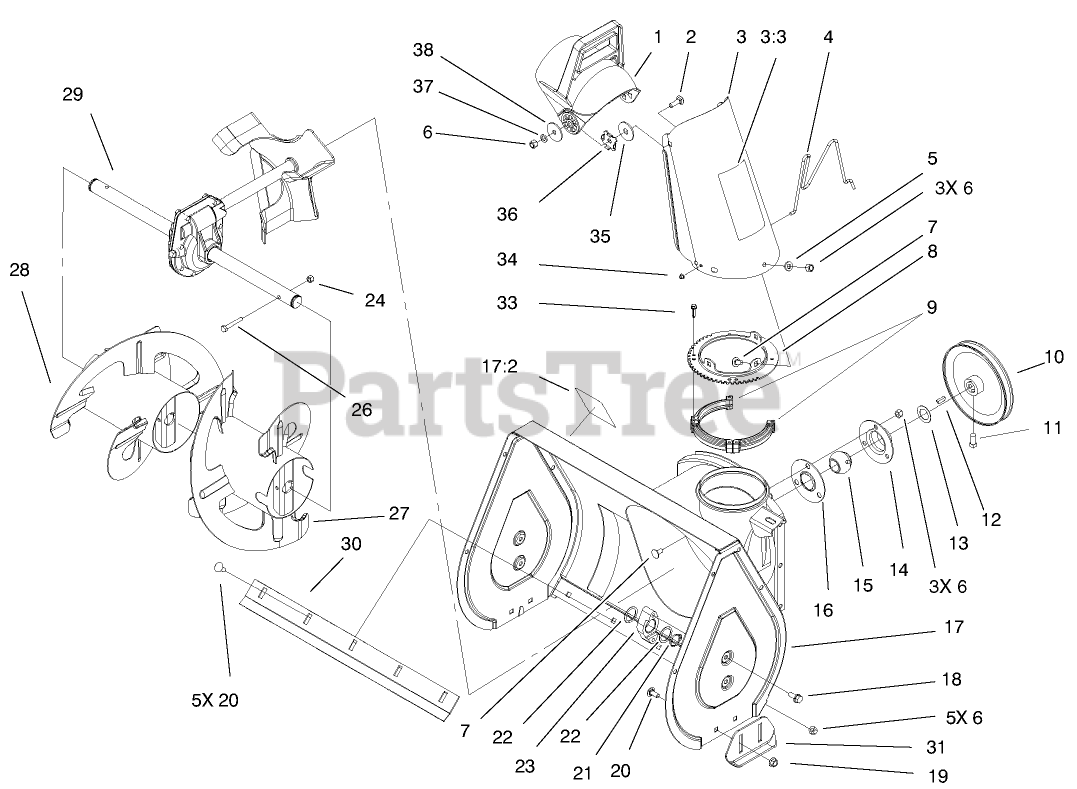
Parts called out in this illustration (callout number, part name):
1	CHUTE-DEFLECTOR
2	SCREW-CARR
3	CHUTE ASM
3:3	DECAL - DANGER
3:3	DECAL-DANGER
4	WIRE-CHUTE
5	WASHER-PLAIN
6	NUT-LOCK, NI
7	SCREW-CARR
8	RING-CHUTE
9	RING-CHUTE, RETAINER
10	PULLEY
11	SCREW-SET, SQH
12	KEY-WOODRUFF
13	WASHER
14	FLANGE-CUP, BEARING
15	BEARING-BALL
16	FLANGE-CUP, BEARING
17	AUGER HOUSING ASM
17:2	DECAL-WARNING, AUGER
18	SCREW-HWHTF
19	NUT-HF
20	BOLT-CARR
21	RING-RETAINING
22	WASHER
24	NUT-LOCK, NI
26	SCREW-HH
27	AUGER ASM-LH, 22"
28	AUGER ASM-RH, 22"
29	22 INCH GEAR CASE ASM
30	BLADE-SCRAPER
33	SCREW-SPECIAL
34	NUT-PUSH
35	WASHER-RUBBER
36	PLATE-FRICTION
37	WASHER-BELLEVILLE
38	WASHER-FLAT
